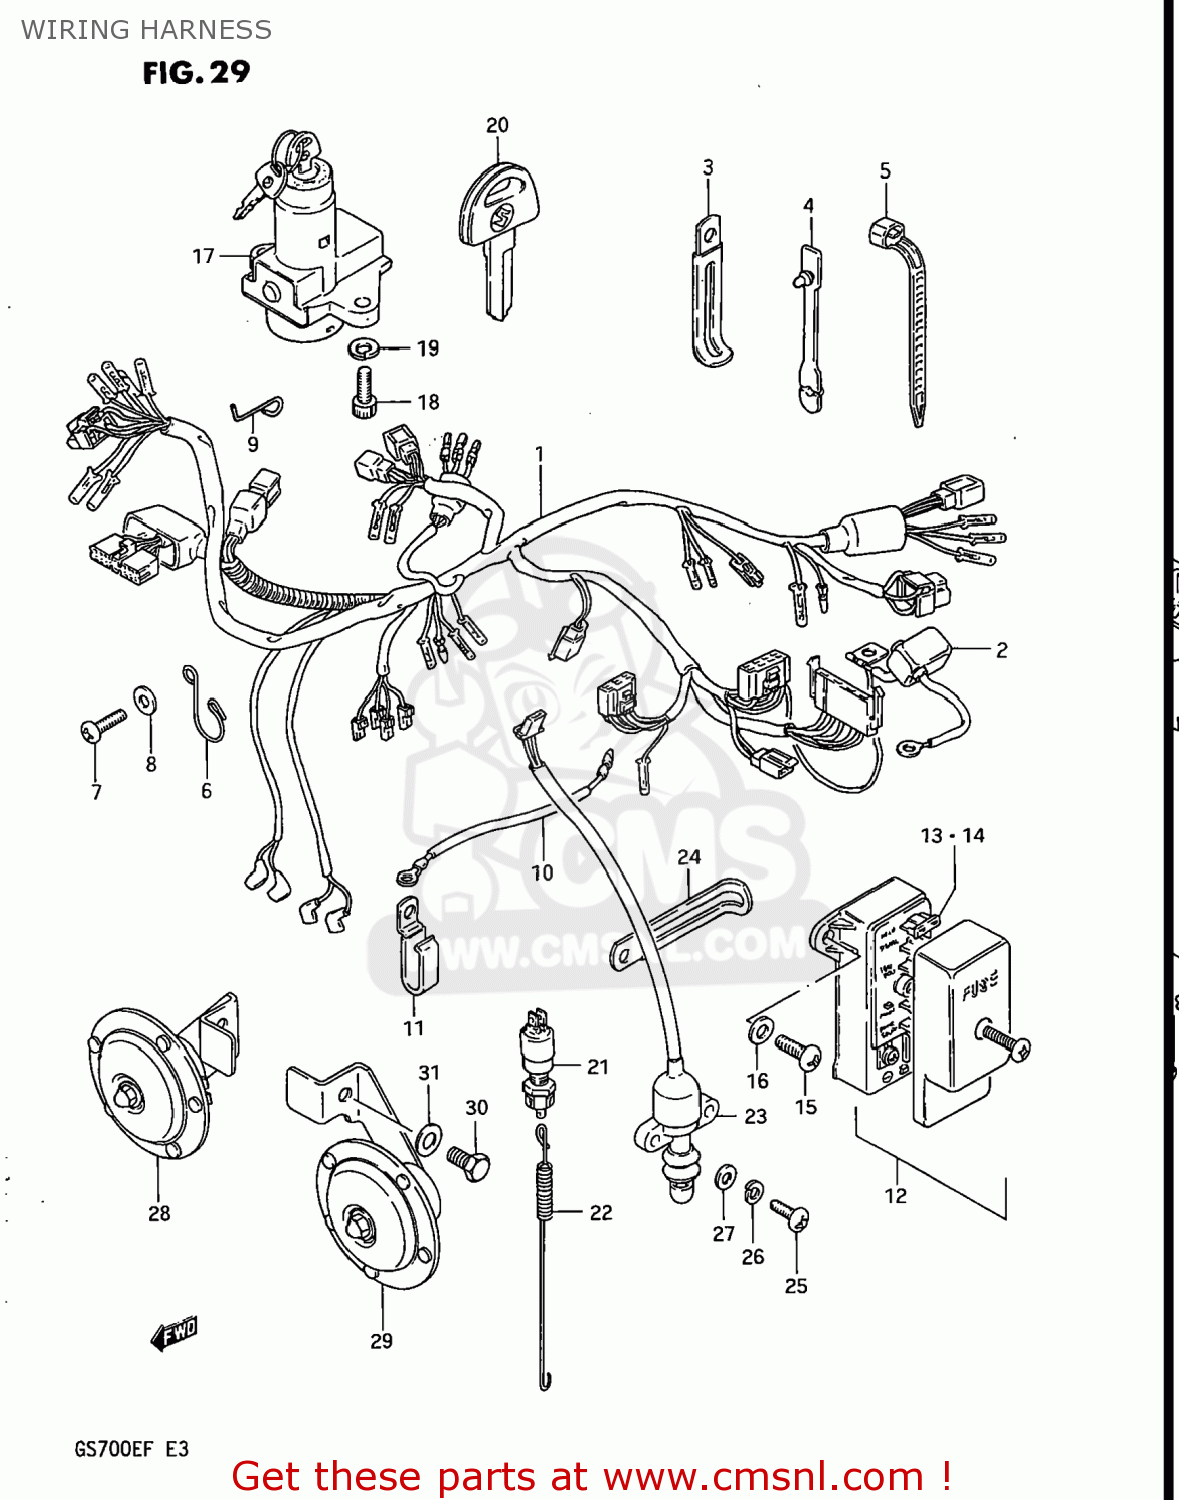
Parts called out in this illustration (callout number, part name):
1	HARNESS,WIRING
2	CAP,BATTERY PLUS TERMINAL
3	CLAMP
4	CLAMP,L:88
5	CLAMP(L:95)
6	CLIP,WIRING HARNESS
7	SCREW 6X12
8	WASHER
9	GUIDE,WIRING HARNESS
10	WIRE
11	CLAMP
12	BOX ASSEMBLY,FUSE
13	FUSE(10A)
14	FUSE(15A)
15	SCREW
16	WASHER, LOWER
17	SWITCH ASSY,IGNITION
18	BOLT
19	LOCK WASHER
20	KEY,BLANK
21	SWITCH ASSEMBLY,STOP LAMP
22	SPRING
23	SWITCH ASSEMBLY,SIDE STAND
24	CLAMP
25	SCREW 5X20
26	WASHER,LOCK
27	WASHER,5MM
28	HORN ASSEMBLY,HIGH PITCH
29	HORN ASSEMBLY,LOW PITCH
30	BOLT
31	WASHER
